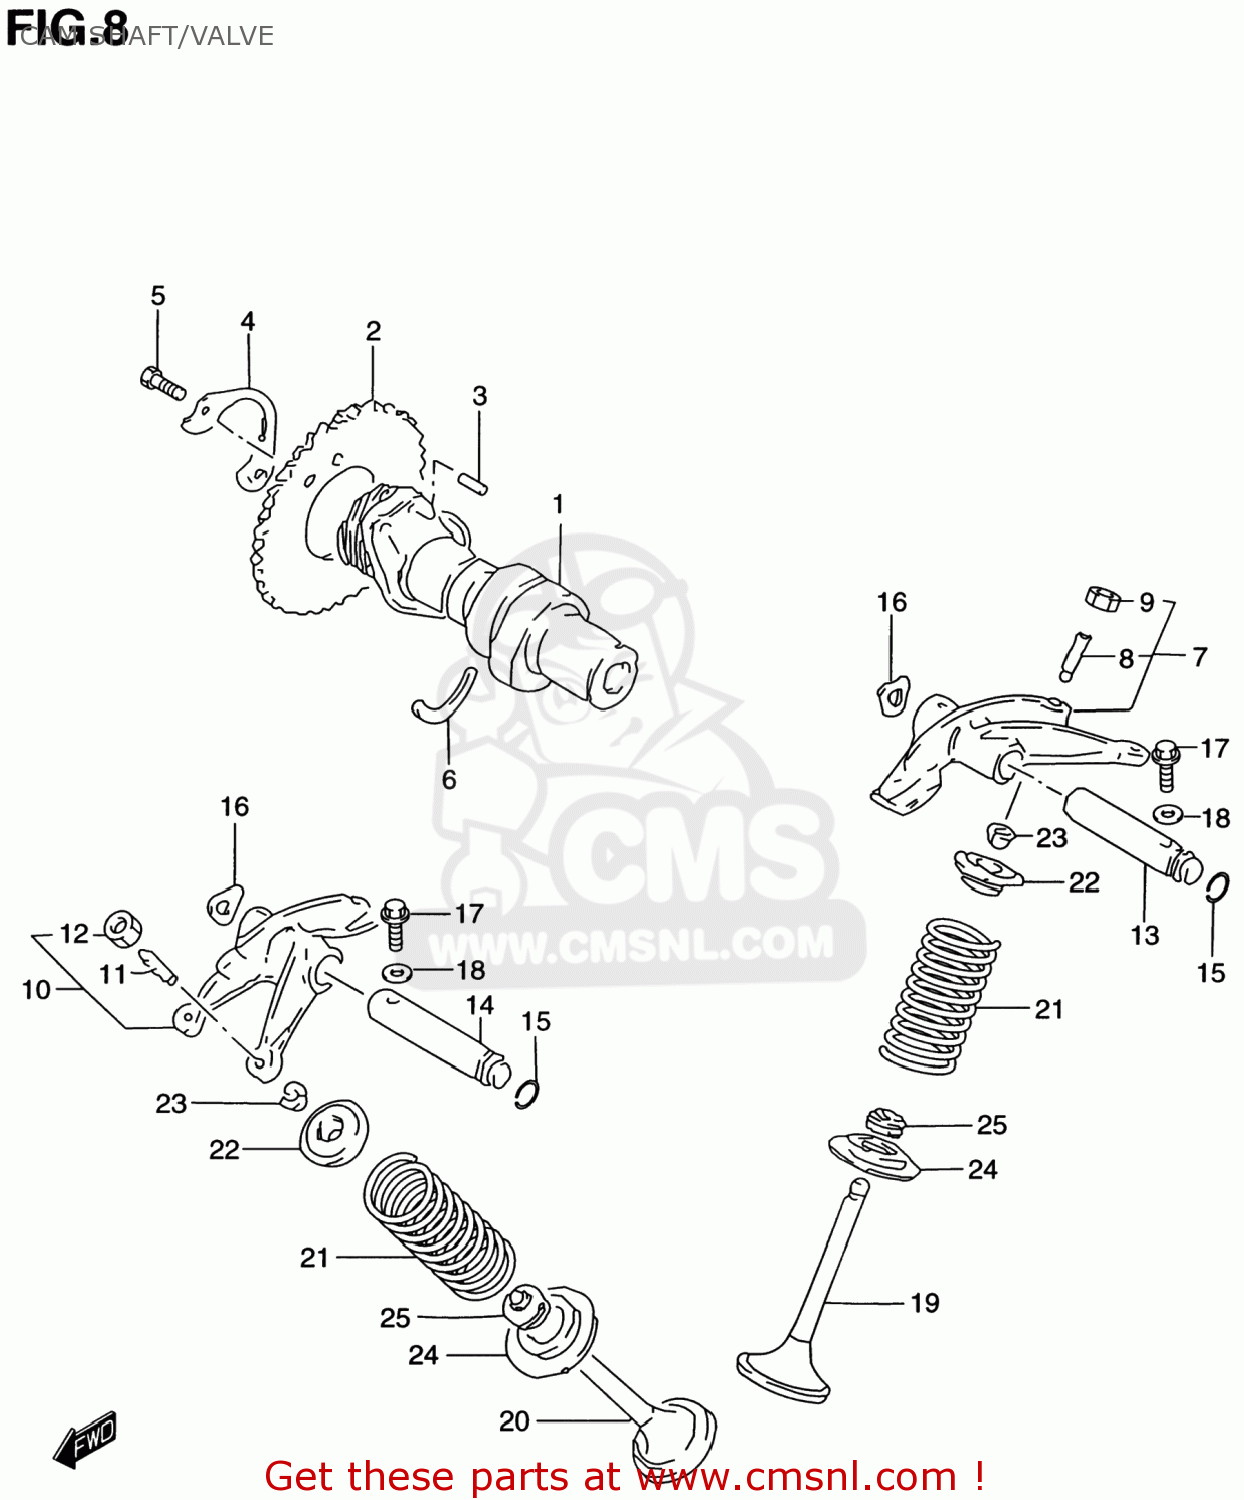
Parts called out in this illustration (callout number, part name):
1	CAMSHAFT
2	SPROCKET,CAMSHAFT(NT:42)
3	PIN
4	WASHER,CAM CHAIN SPROCKET
5	BOLT(6X12.5)
6	C RING
7	ARM,VALVE ROCKER INTAKE
8	SCREW,TAPPET ADJUSTING
9	NUT,TAPPET ADJUSTING
10	ARM,VALVE ROCKER EXHAUST
11	SCREW,TAPPET ADJUSTING
12	NUT,TAPPET ADJUSTING
13	SHAFT,VLV ROCKER ARM IN(L:91.5
14	SHAFT,VLV ROCKER ARM EXH(L:76)
15	O RING(D:1.9,ID:8.6)
16	WASHER
17	BOLT
18	GASKET(5.8X13X1.2) (NAS)
19	VALVE,INTAKE
20	VALVE,EXHAUST
21	SPRING,VALVE
22	RETAINER,VALVE SPRING
23	COTTER VALVE
24	SEAT,VALVE SPRING
25	SEAL,OIL(5.5X11X8.2)
